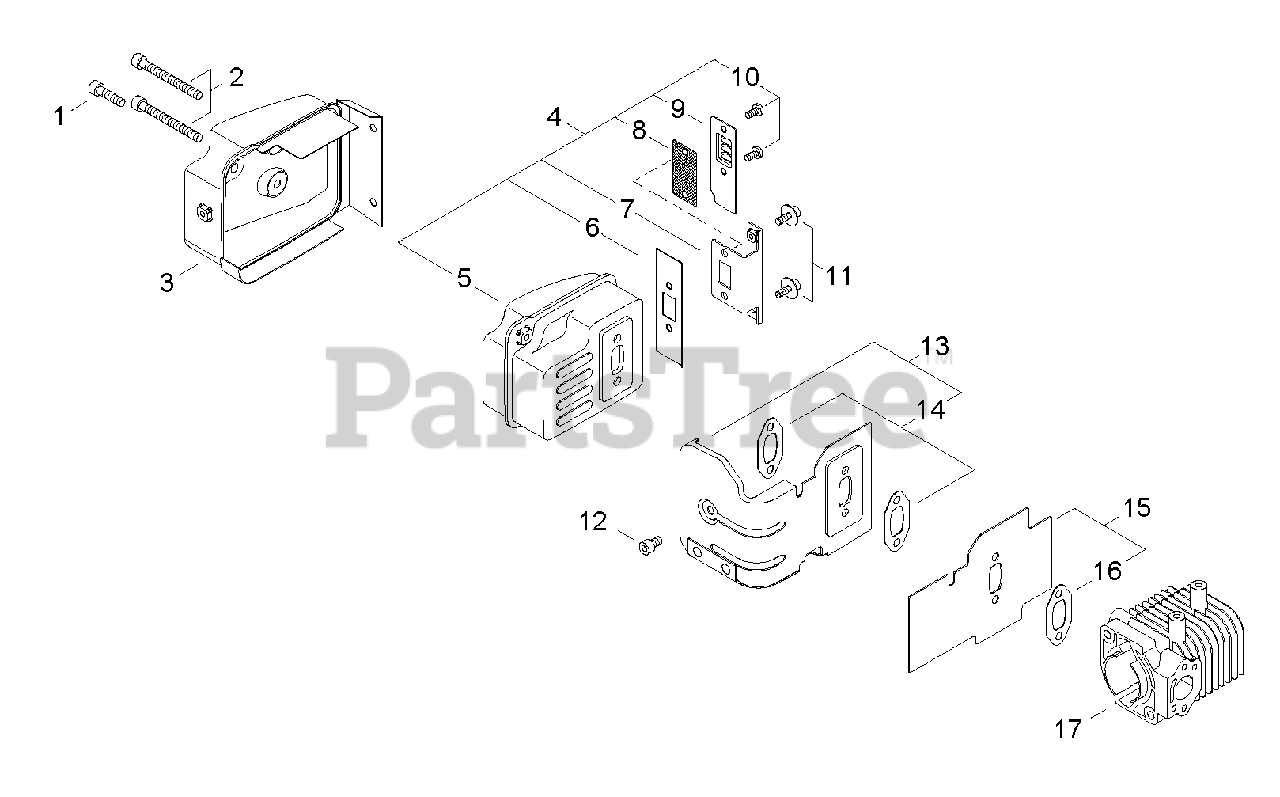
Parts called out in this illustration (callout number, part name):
1	BOLT CB-5×20
2	BOLT M5
3	COVER, MUFFLER
4	MUFFLER ASSY
5	MUFFLER
6	PLATE, MUFFLER
7	STAY, MUFFLER
8	SCREEN, SPARK ARRESTER
9	OUTLET, EXHAUST
10	SCREW 4×8
11	SCREW M4×8
12	BOLT 5×8
13	DEFLECTOR ASSY, EXHAUST HEAT
14	GASKET, EXHAUST
15	SHIELD ASSY, EXHAUST HEAT
16	GASKET, EXHAUST
17	CYLINDER
